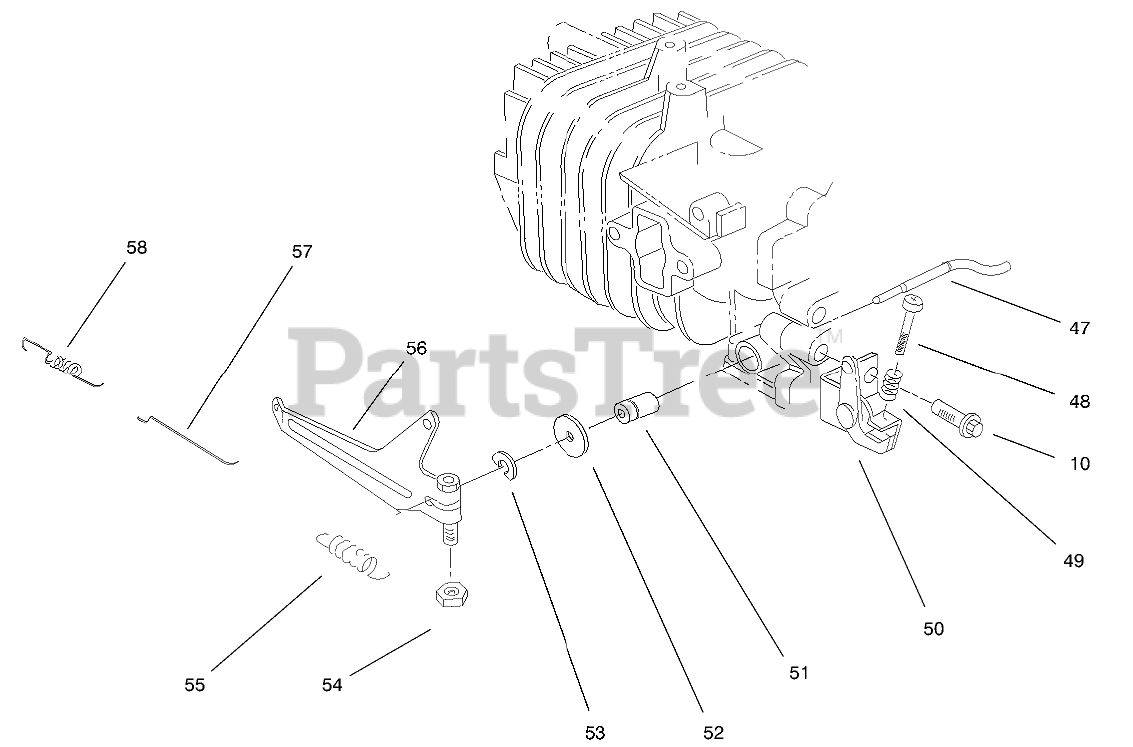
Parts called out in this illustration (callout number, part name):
47	SHAFT
48	SCREW
49	SPRING
50	GOV SPR BRKT
51	SEAL-OIL
52	WASHER
53	E-RING
55	GOV SPRING
56	GOV ARM
57	CARB ROD
58	CARB SPRING
78	SCREW
79	GASKET
